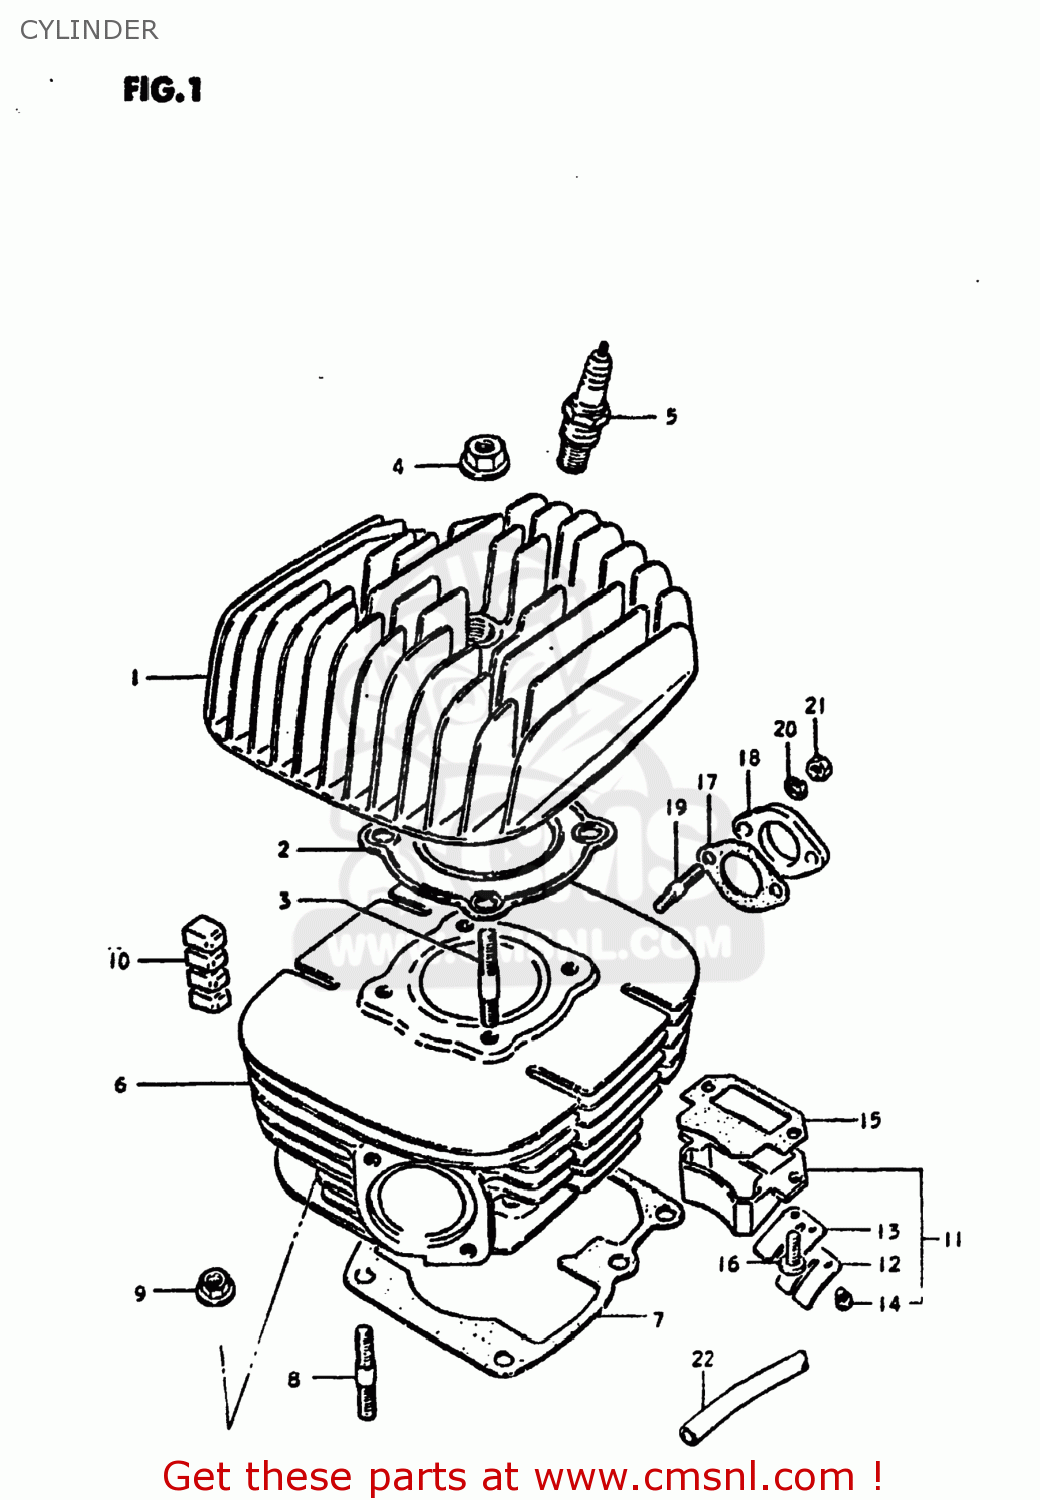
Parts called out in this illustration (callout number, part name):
1	HEAD,CYLINDER
2	GASKET,CYLINDER HEAD (MCA)
3	STUD BOLT
4	NUT
5	PLUG,SPARK
6	CYLINDER
7	GASKET,CYLINDER (MCA)
8	STUD 8X25
9	NUT
10	PAD,CYLINDER
11	VALVE ASSEMBLY,REED
12	STOPPER,REED VALVE
13	VALVE,REED
14	SCREW,REED VALVE
15	GASKET,REED VALVE (MCA)
16	SCREW
17	GASKET,CARBURETOR (MCA)
18	INSULATOR,CARBURETOR
19	STUD BOLT
20	LOCK WASHER
21	NUT
22	HOSE
